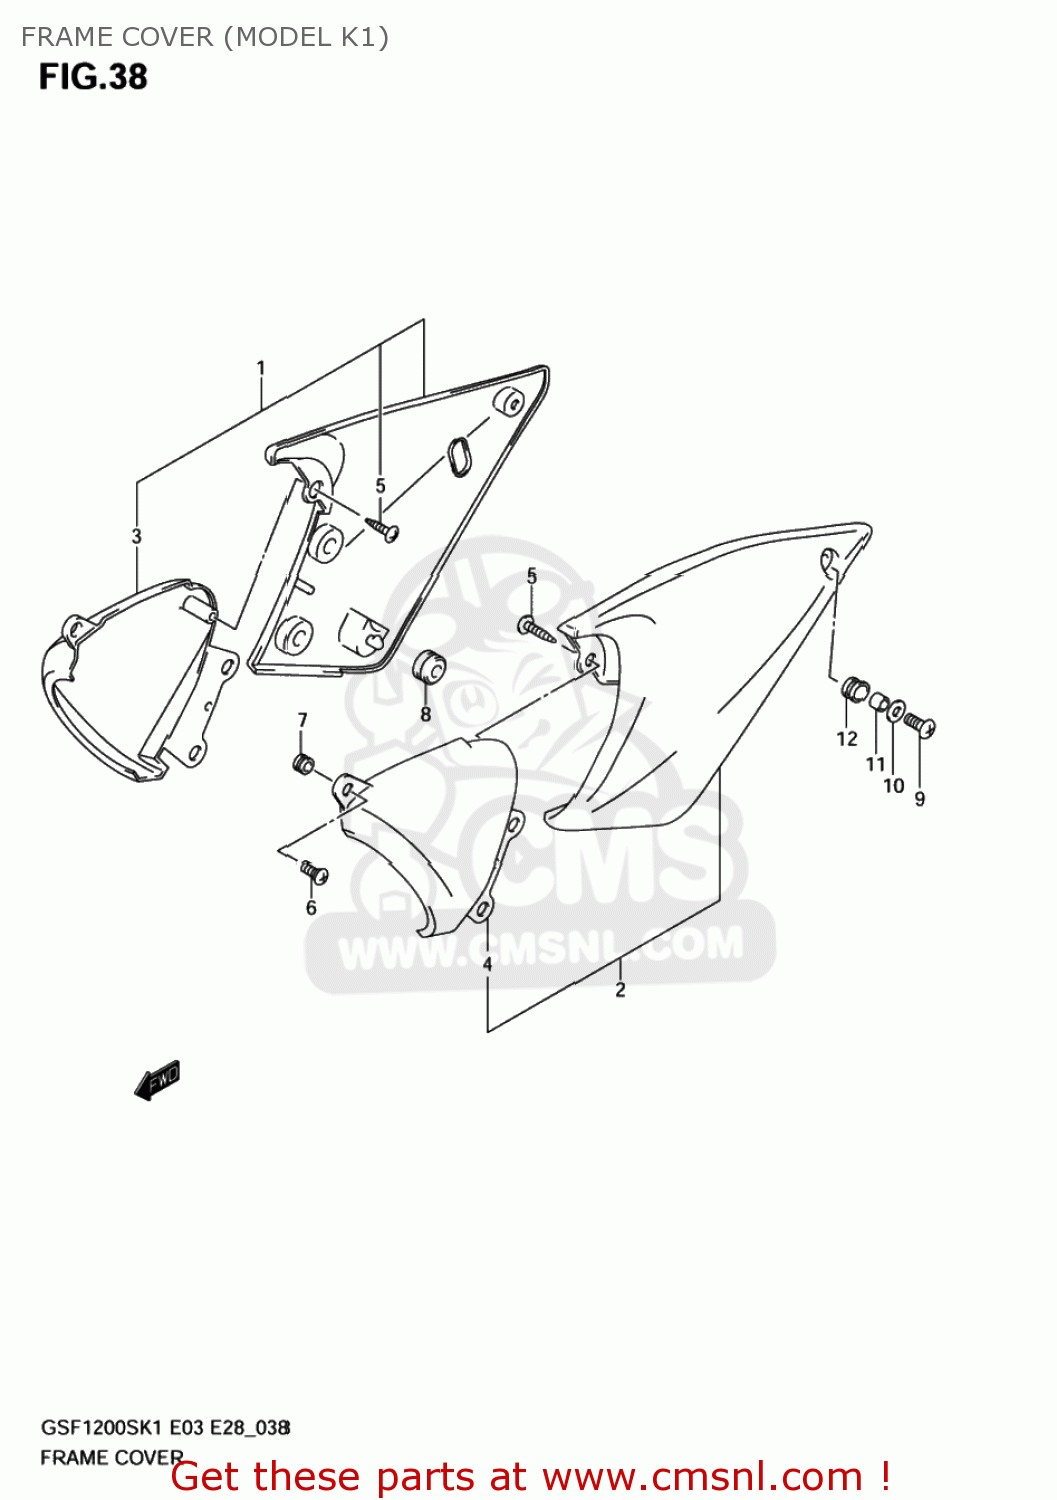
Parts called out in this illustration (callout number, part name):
1	COVER,FRAME,R(GRAY)
2	COVER,FRAME,L(GRAY)
3	COVER,FRAME FR,R
4	COVER,FRAME FR,L
5	SCREW
6	SCREW,FRAME COVER,FRONT
7	CUSHION,FRAME COVER FR
8	CUSHION
9	SCREW(6X16)
10	WASHER(6.5X18X1)
11	SPACER(6.5X9X9)
12	CUSHION
